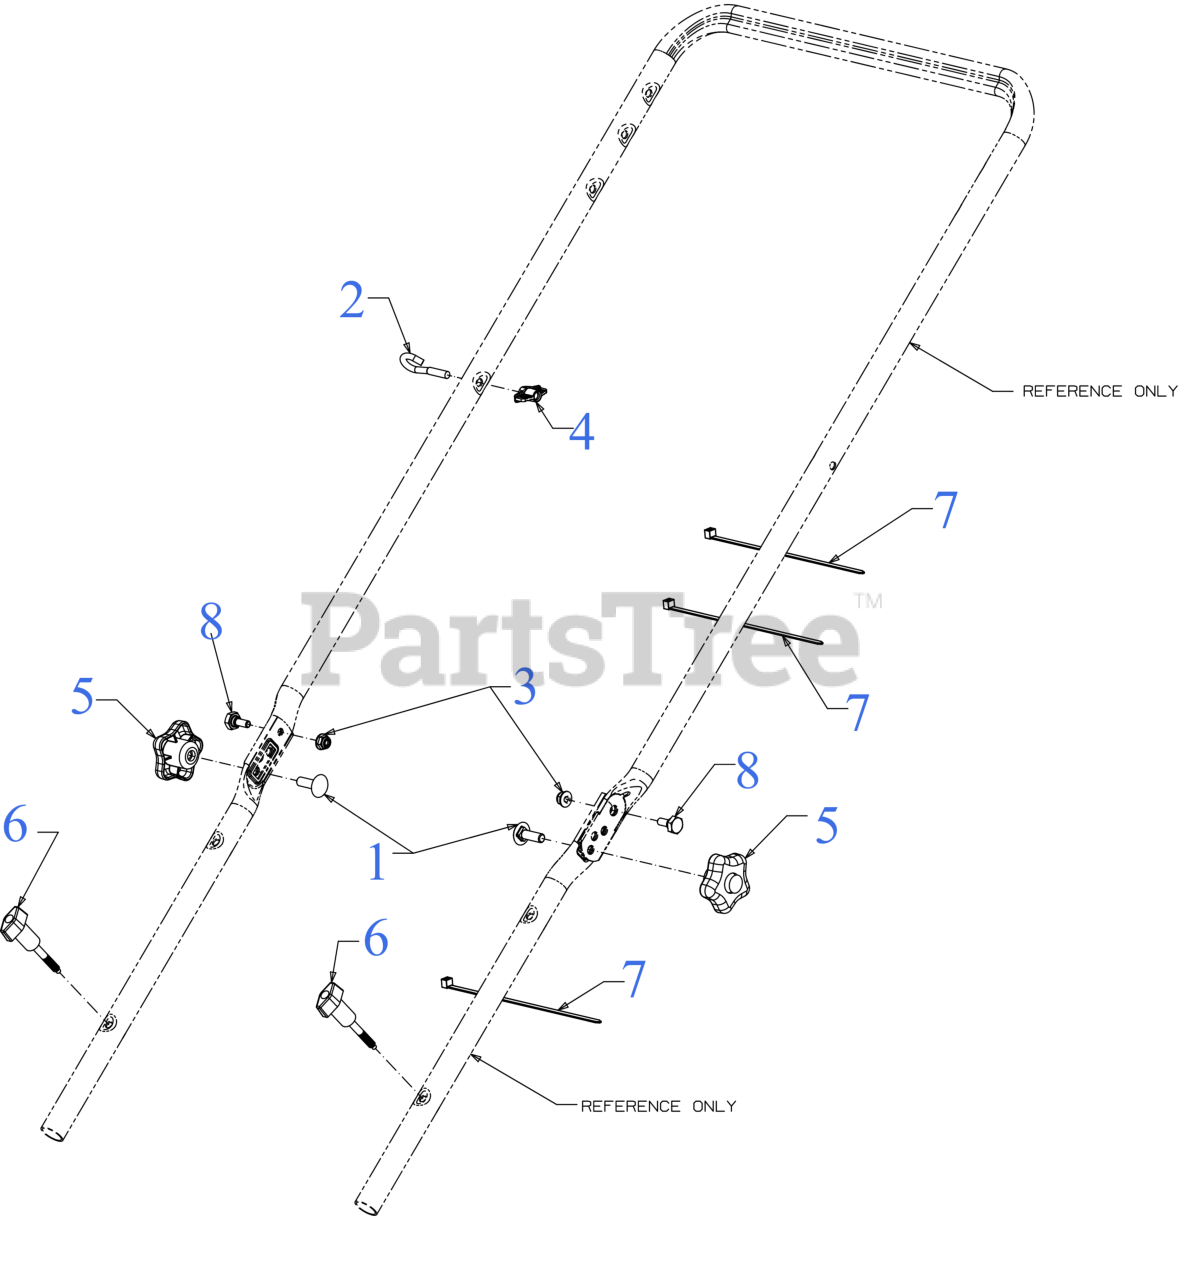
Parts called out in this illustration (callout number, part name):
1	SCREW 5/16-18 x 1.00 GR5
2	EYEBOLT 1/4-20
3	FLANGE LOCK NUT
4	HANDLE KNOB
5	STAR KNOB- YELLOW
6	WING KNOB 1/4-20
7	7" CABLE TIE
8	SHOULDER SCREW
